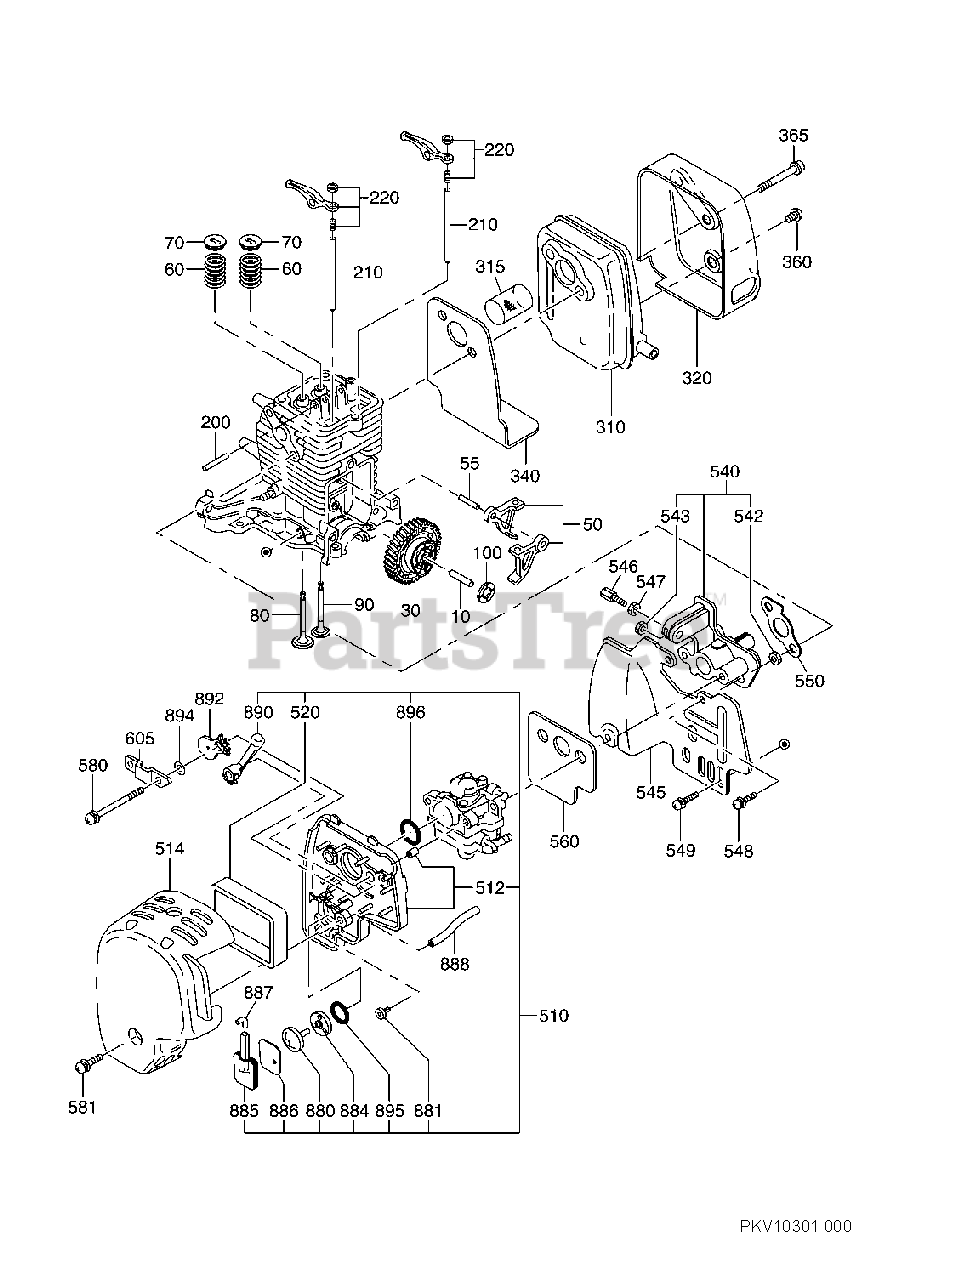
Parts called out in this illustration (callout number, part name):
510	PLATE, CLEANER AY
512	PLATE, AIR CLEANER CP
514	COVER, AIR CLEANER
884	PLATE, CHECK VALVE
885	PLATE, SEPARATOR
886	GASKET, SEPARATOR
